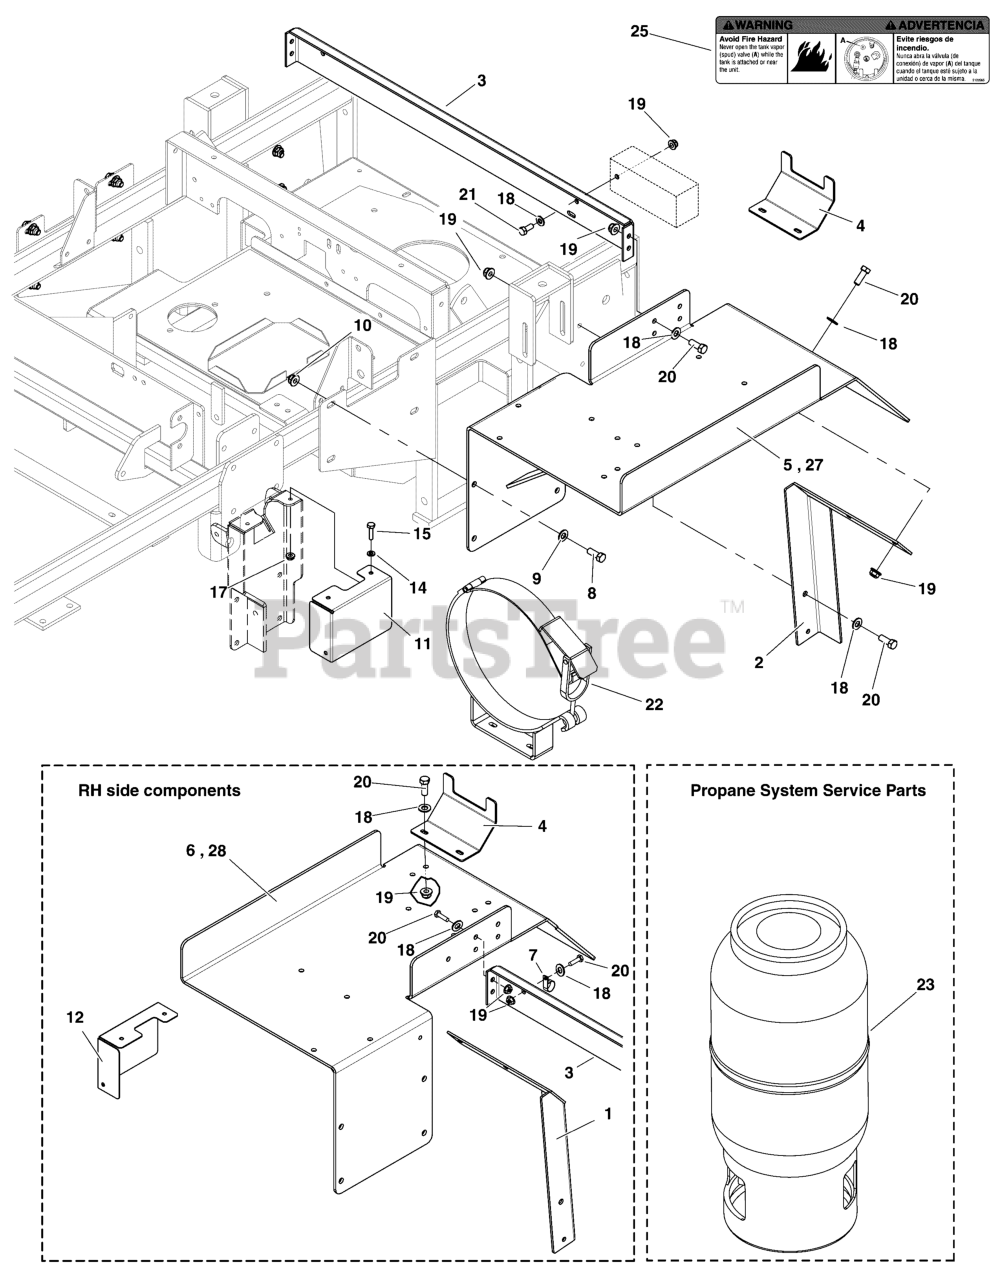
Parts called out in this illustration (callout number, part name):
1	WELD, TANK MOUNT, PROPANE, RH - RED
2	WELD, TANK MOUNT, PROPANE, LH - RED
3	PLATE, BRACKET, REGULATOR MOUNT, PROPANE - RED
4	PLATE, BRACKET, TANK MOUNT - RED
5	WELD, TANK MOUNT - LH
6	WELD, TANK MOUNT - RH
7	CLAMP, VINYL INSULATED, 1.00
8	BOLT, 3/8-16 X 1" GD5 CZ
9	WASHER, 3/8 SAE
10	NUT, 3/8 - 16 HEX NYLOCK FLANGE
11	PLATE, SWITCH, GUARD, LH - RED
12	PLATE SWITCH GUARD RH - RED
13	BOLT, 1/4-20 X 2", GD5
14	WASHER, 1/4 SAE
15	BOLT, 1/4-20 X 1" GD5 CZ
17	WASHER, 3/8 SAE
18	WASHER, 5/16" SAE
19	NUT, 5/16-18 HEX NYLOCK FLANGE NUT
20	BOLT, 5/16-18 X 1" GRD5 YZ
21	BOLT, 5/16-18 X 1-1/2" GD5 YZ
23	TANK, PROPANE - WORTHINGTON
24	ENGINE, BRIGGS & STRATTON, PROPANE READY
26	DECAL, WARNING, VAPOR VALVE
27	WELD, TANK MOUNT - LH
28	WELD, TANK MOUNT - RH
